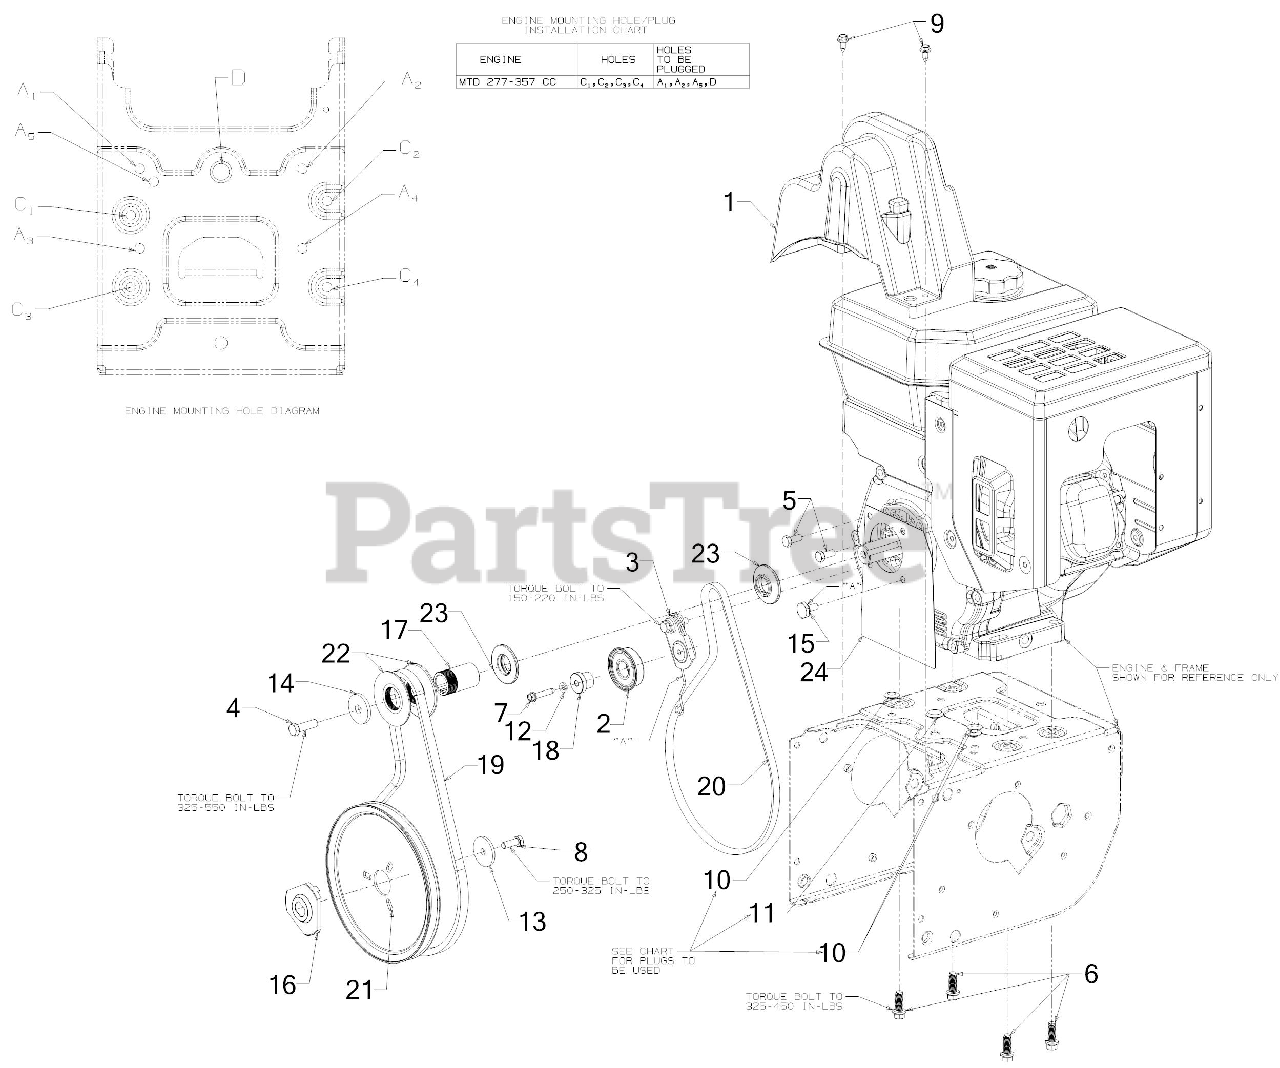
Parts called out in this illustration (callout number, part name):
1	BELT COVER (LARGE BLOCK)
2	IDLER PULLEY ASSEMBLY
3	SCREW 5/16-24 x 1.25 GR5
4	SCREW 3/8-24X1.25
5	SCREW 5/16-24 x .750 GR5
6	SCREW 3/8-16 x 1
7	SCREW 1/4-20 x 1.25
8	SCREW 5/16-24 x .875 GR5
9	SCREW 1/4-20X.625
10	PLUG-3/8 DIA ID x 3/32
11	PLUG-1/2 ID x 3/32
12	LOCK WASHER
13	FLAT WASHER
14	FLAT WASHER .45 x 1.5 x .172 HT
15	SHOULDER SCREW
16	ADAPTER PULLEY .75 DIA W/DD
17	PULLEY SPACER
18	SHOULDER SPACER
19	BELT-.500 x 37
20	V-BELT 3/8 x 35.68"
21	AUGER PULLEY
22	HALF PULLEY 4L V x 2.6 OD
23	HALF PULLEY-3/8 V x 1.7160
24	ENGINE PLATE (FRONT COVER)
